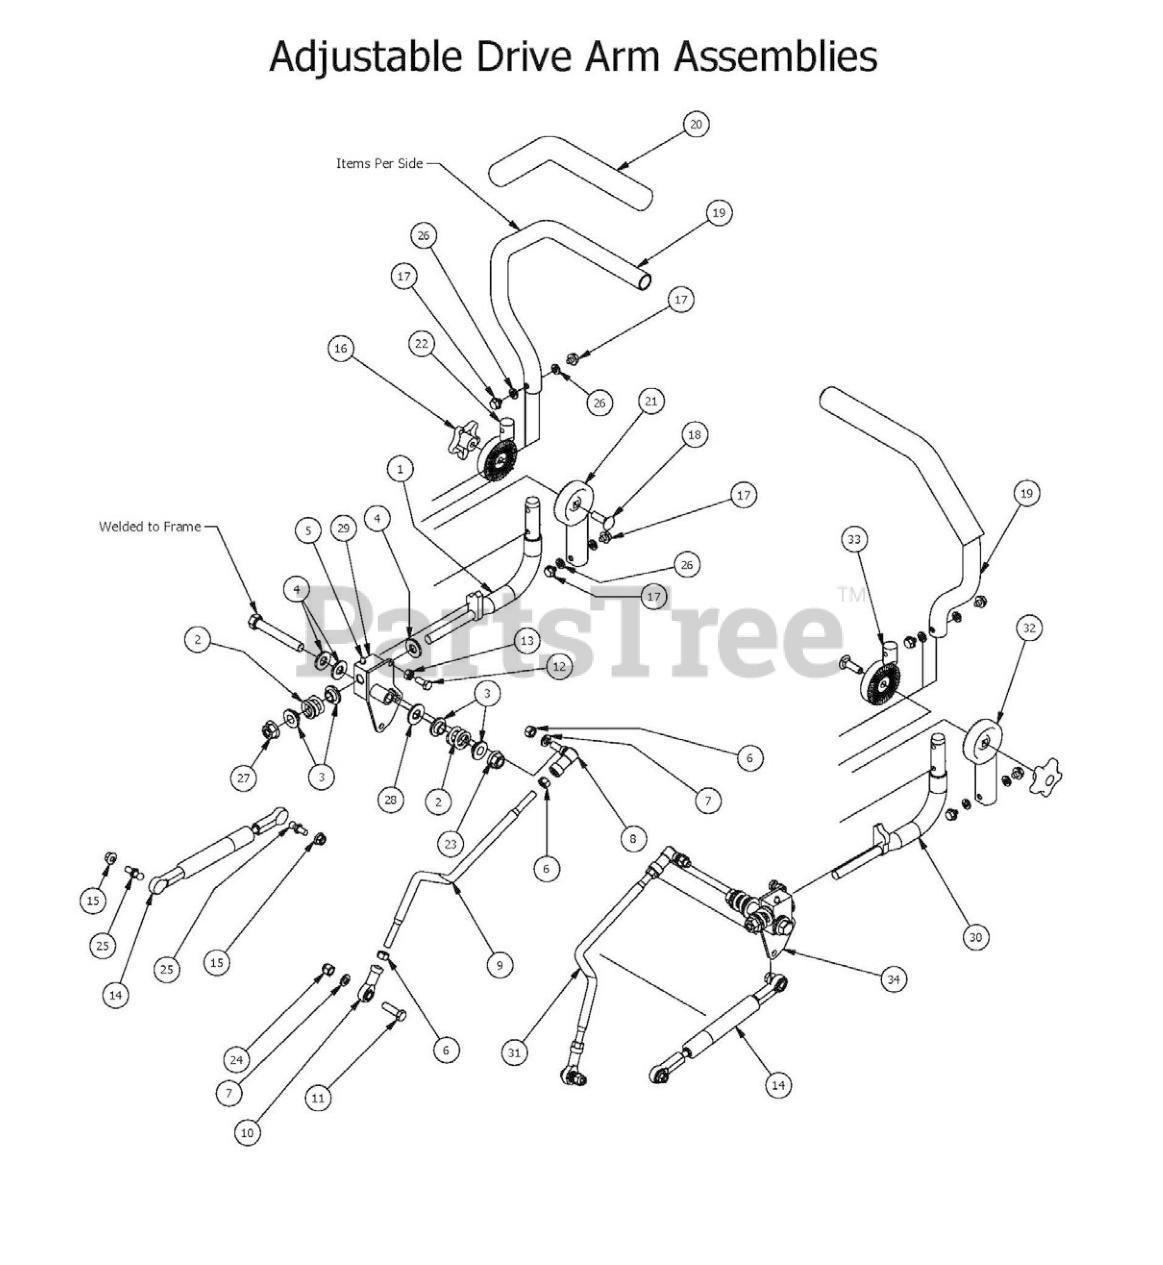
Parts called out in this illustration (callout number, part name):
1	Steering Arm Elbow - Left
2	Drive Lever Spring
3	.515 ID Nylon Shoulder Washer
4	505 Nylon Spacer
5	1/4" Press in Grease Fitting
6	3/8" Fine Threaded Jam Nut
7	3/8" Lock Washer
8	3/8-24 Quick Release Ball Joint
9	Push Rod Left
10	Spherical Rod End - Outlaw
11	3/8" x 1 1/4" Hex Bolt
12	5/16" x 3/4" Hex Bolt
14	Steering Damper
15	5/16" Flange Nut
16	Black Knob for Adjustable Steering Arm
17	5/16-18 1/2 HWH Bolt-Steering
18	3/8" x 1 1/4" Carriage Bolt
19	Upper Tube-Adjustable Steering
20	Black Steering Grip
21	Lower Adjuster Steering Arm- Left
22	Upper Adjuster-Steering Arm- Left
23	1/2-13 Hex Flange (GR.G) ZC
24	3/8 Nylock Nut
25	10mm Damper Ball Stud-Steering
26	5/16" Lock Washer
27	1/2-13 Nylon Insert Flange Nut Zinc Orange Nylon
28	1/2" Washer (Grade 8)
29	2017 Drive Lever Housing - Left
30	Steering Arm Elbow - Right
31	Push Rod - Right
32	Lower Adjuster Steering Arm- Right
33	Upper Adjust Steering Arm- Right
34	2017 Drive Lever Housing - Right
